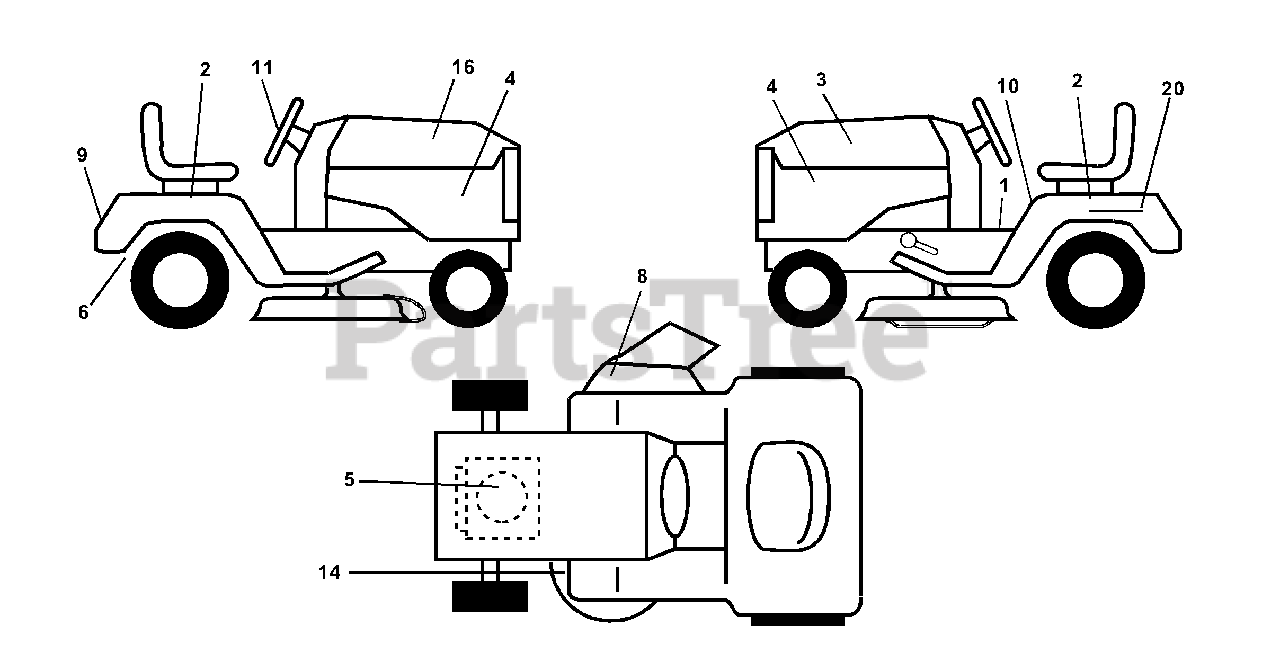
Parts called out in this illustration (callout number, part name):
1	Decal Oper
2	Decal Fender Auto
3	Decal Hood LH
4	Decal Side Panel Logo
5	Decal HP Engine
6	Decal By Pass Lt Hydro
8	Decal Mower Warn Keep Hand Away
9	Decal Fender Logo
10	Decal Fender Danger E/F
11	Decal Ins Strg Whl
14	Decal V-Belt Schematic
16	Decal Hood Rh
20	Decal Bat Dan/Psn
